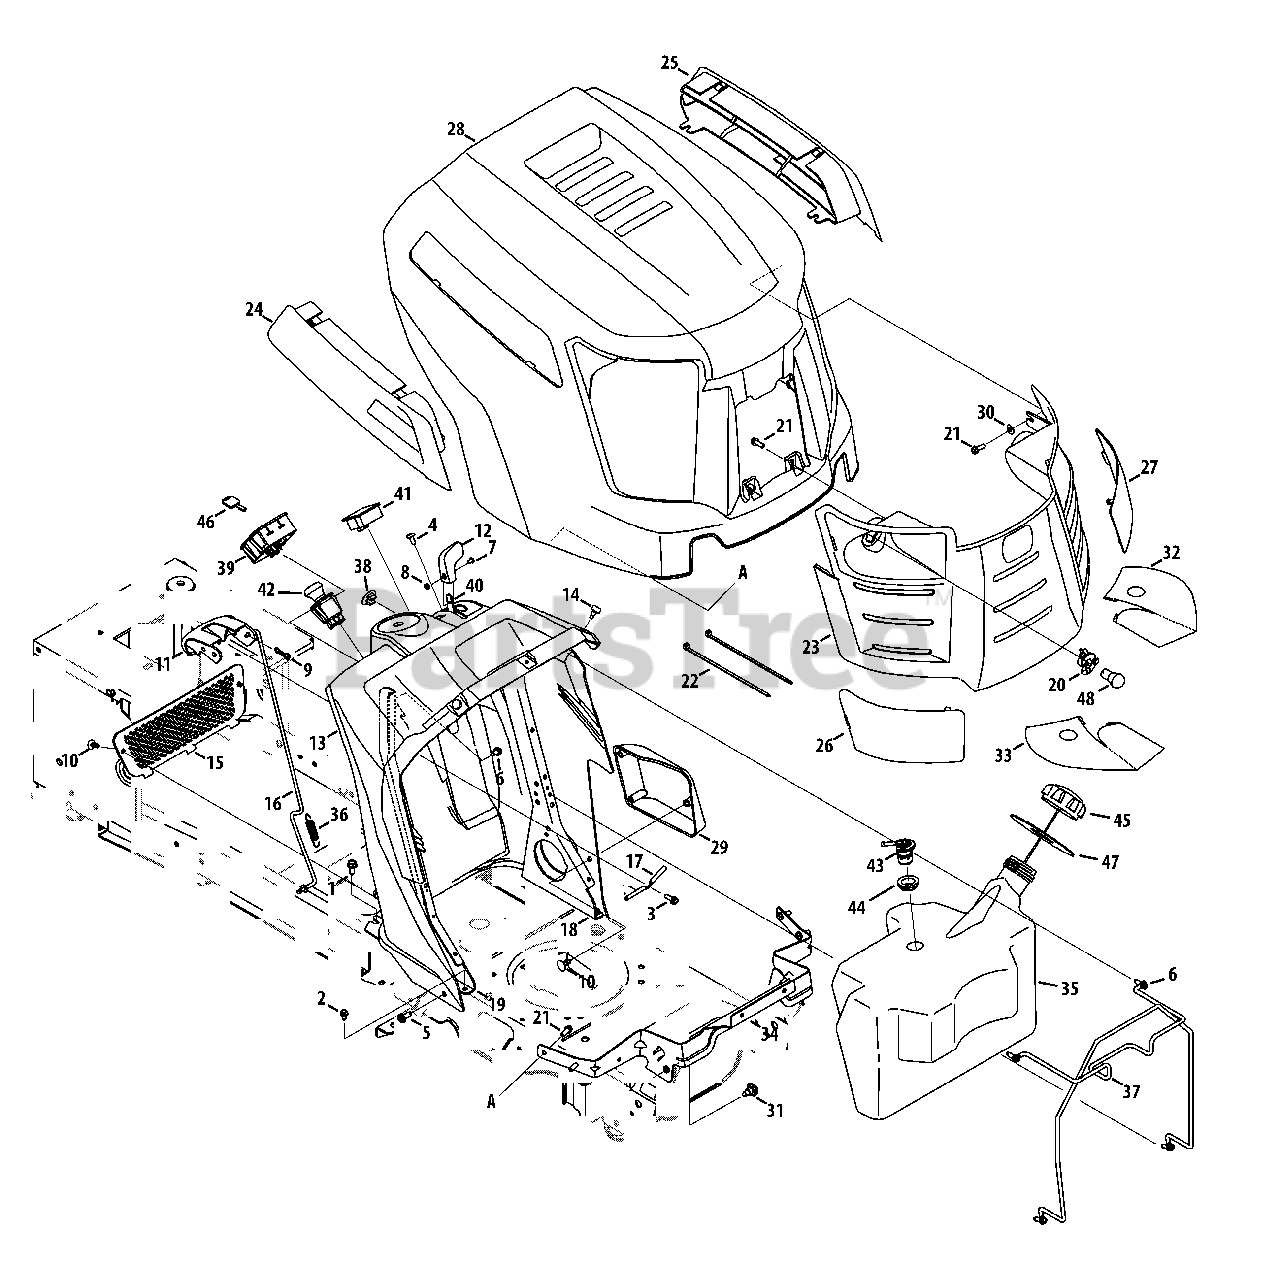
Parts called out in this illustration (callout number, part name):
1	Screw, Self-tapping, 5/16-18, .750
2	Screw, Self-tapping, 1/4-20, 0.500
3	Screw, HL, 1/4-15, 0.750
4	Screw, Ab, 1/4-14, 0.625,
5	Screw, Self-tapping, 5/16-18, 0.750,
6	Screw, Self-tapping, 1/4-20 x .625
7	Screw, Mach, #8-32, 0.375
8	Nut, Hex, #8-32
9	Pin, Cotter, Bow-Tie 72
10	Clip, Ratchet, .250 Dia
11	Lever, Dash, Cruise/Brake
12	Knob, Throttle
13	Dash Panel, A-Style
14	Bumper, .62 Dia X .3
16	Rod, Control, Latch Cub
17	Rod, Lever, Bent
18	Support, Dash, Plate LH
19	Support, Dash, Plate RH
20	Socket, Lamp
21	Screw, 1/4 Dia, .750
22	Tie, Cable, Push Mount 7.5 Lg
23	Grille Ass’y (Incl. 26, 27, 32 & 33)
24	Scoop, Hood, RH A-Style
25	Scoop, Hood, LH A-Style
26	Lens, Hood, RH A-Style
27	Lens, Hood, LH A-Style
28	Hood, A-Style
29	Cover, Power Steering Motor
30	Washer, Flat, .271, .630, .065
31	Screw, Shoulder, .43x.29, 5/16-18
32	Reflector, Cub A Style, LH
33	Reflector, Cub A Style, RH
34	Bracket, Pivot, Hood A-Style
35	Tank, Fuel, 3.30 Gal.
36	Spring, .500 Dia. x 2.733
37	Rod, Support, Fuel Tank
38	Plug, Choke
39	Module Switch, Ignition
40	Cable, Throttle/Choke, 38"
41	Meter, Indicator
42	Switch, Electric PTO, Yellow
43	Valve, Rollover Grommet
44	Grommet, Rubber, 23.0 ID
45	Cap, Fuel
46	Key, Assembly
47	Gasket, Fuel Tank
48	Lamp, 12v
